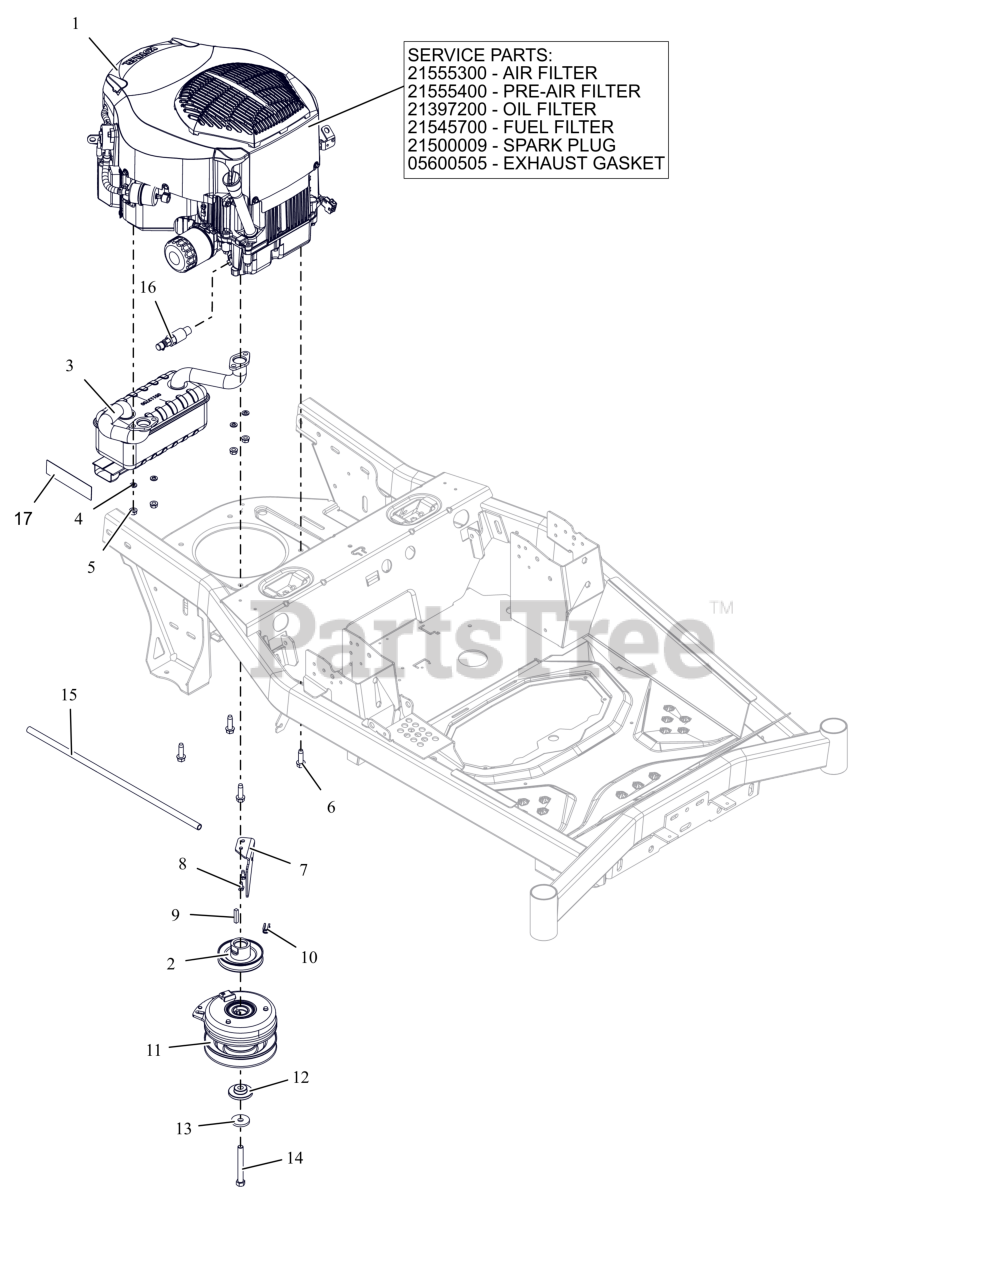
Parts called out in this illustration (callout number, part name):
1	ENGINE, KOHLER - KT740
1	AIR FILTER, KOHLER
1	PRE CLEANER, KOHLER
1	FILTER, OIL - KOH CV20
1	FILTER-FUEL KOHLER COURAGE PRO
1	PLUG, SPARK KOHLER
1	GASKET, MUFFLER KOHLER TWIN
2	WLDMT-PULLEY-4.831OD X1.003
3	MUFFLER, KOHLER
4	WSHR,LK-REG .312X.078 ZCC
5	NUT-LK-TOP-FLG .312-18 GF ZCC
6	SCR,TAP .375-16X1.25HWH TR ZCC
7	BRKT- CLUTCH STOP
8	SCR-TAP .25-20X.50 HWH ZCC
9	KEY-SQ .25 X 1.25 X .25 SAE
10	BSHG, CLUTCH
11	CLUTCH, WARNER-IXR-18211
12	BSHG-FLG .469X1.06X.574X2.0
13	WASHER, 7/16" SPRING DISK
14	BLT- HEX .44-20X3.50 G8 ZCC NT
15	HOSE- OIL DRAIN
16	DRAIN, OIL
17	TAPE, HEAT
